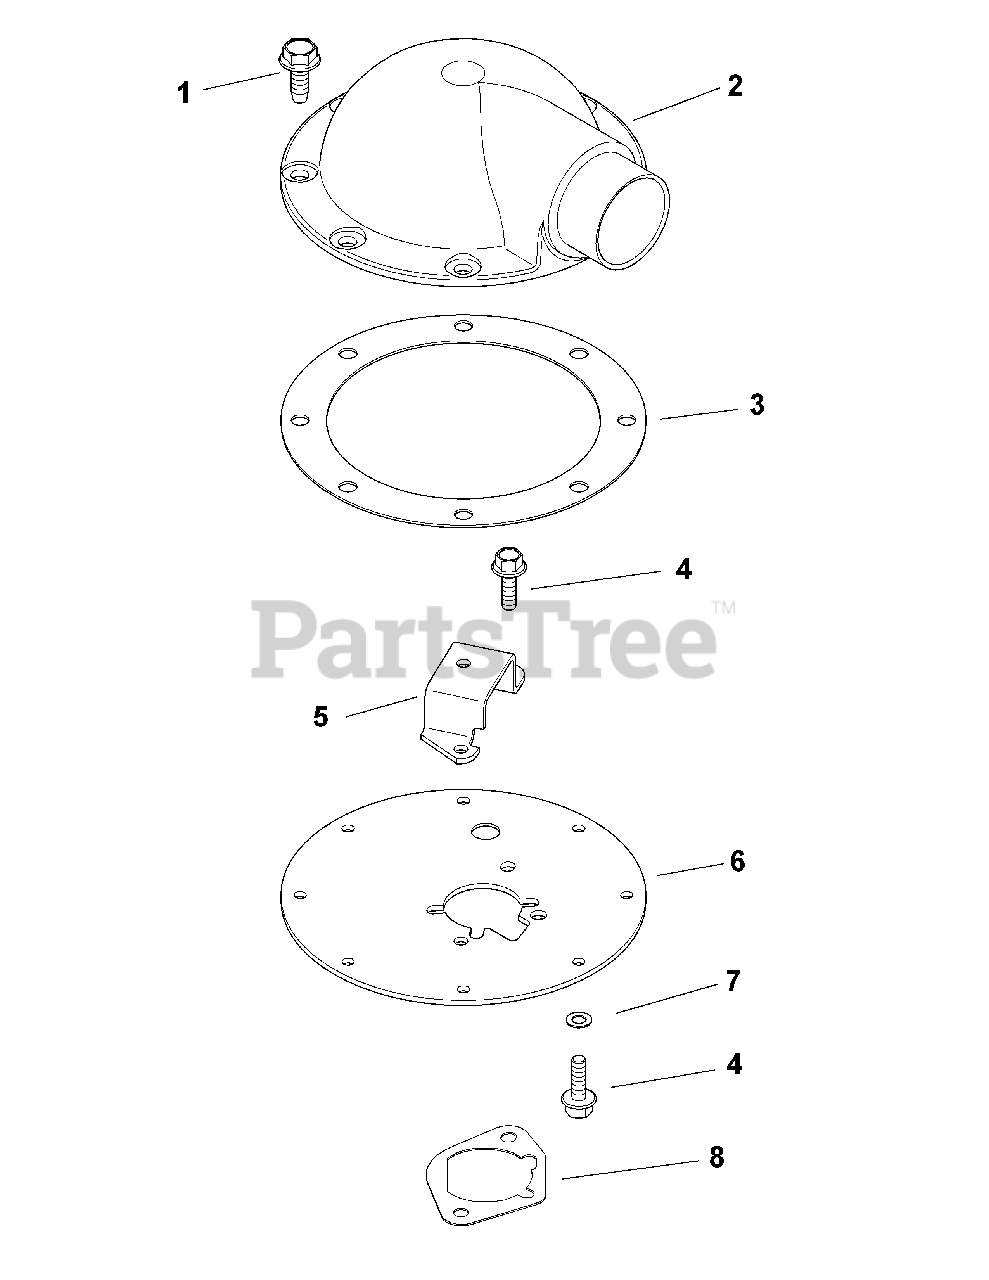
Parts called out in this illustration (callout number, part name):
1	Screw,Flg Thd Frm M6x1.0x16-(#25086397S)
2	Adapter, Air Intake
3	Gasket, Air Cleaner Adapter
4	Screw, Hvy Flg M5x.8X16
5	Bracket, Air Cleaner
6	Adapter, Plate
8	Gasket, Air Cleaner Base
